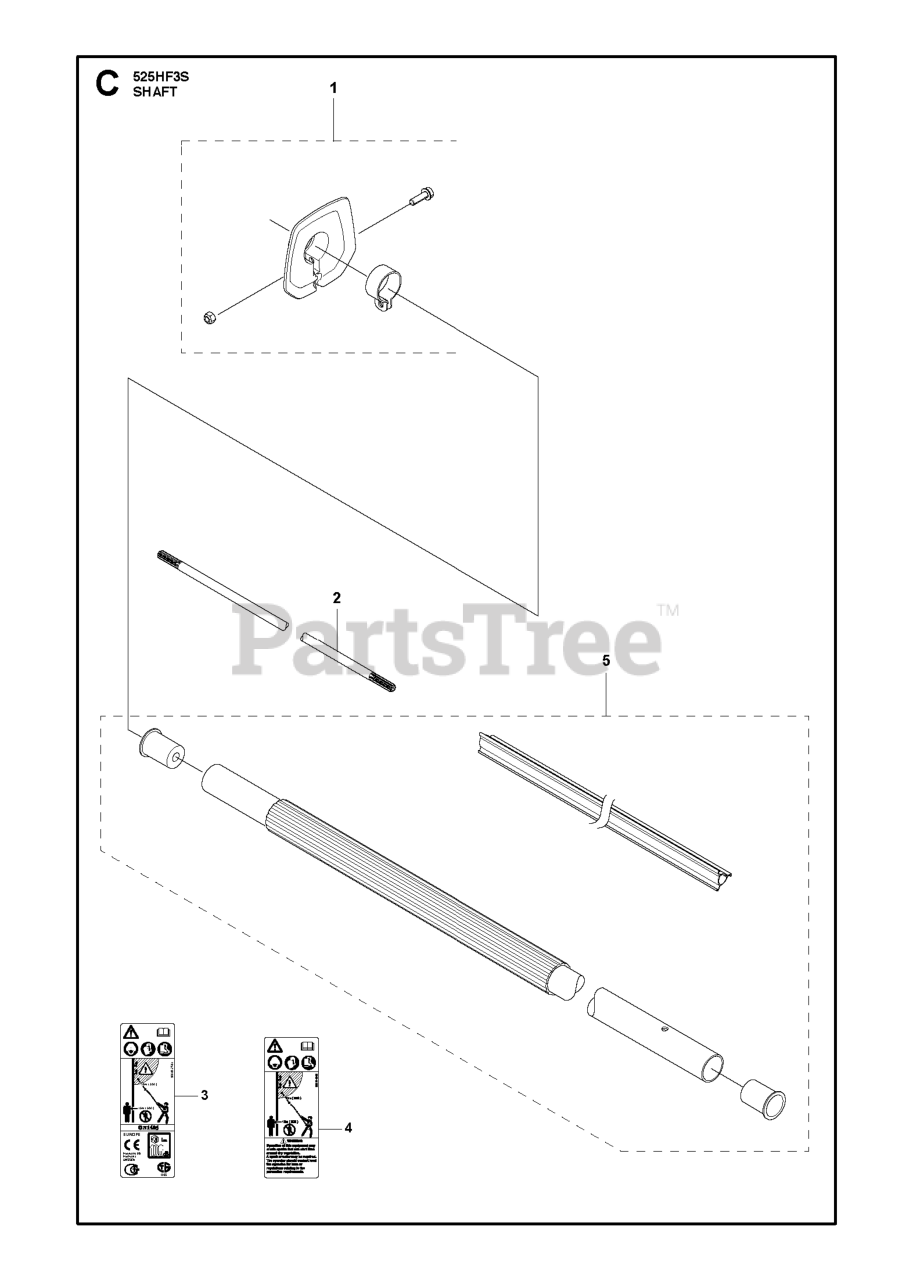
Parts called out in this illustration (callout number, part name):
1	HANDGUARD ASSY
2	DRIVESHAFT 525HF3S
4	DECAL WARNING SPARK ARRESTOR
5	TUBE ASSY W/GRIP
